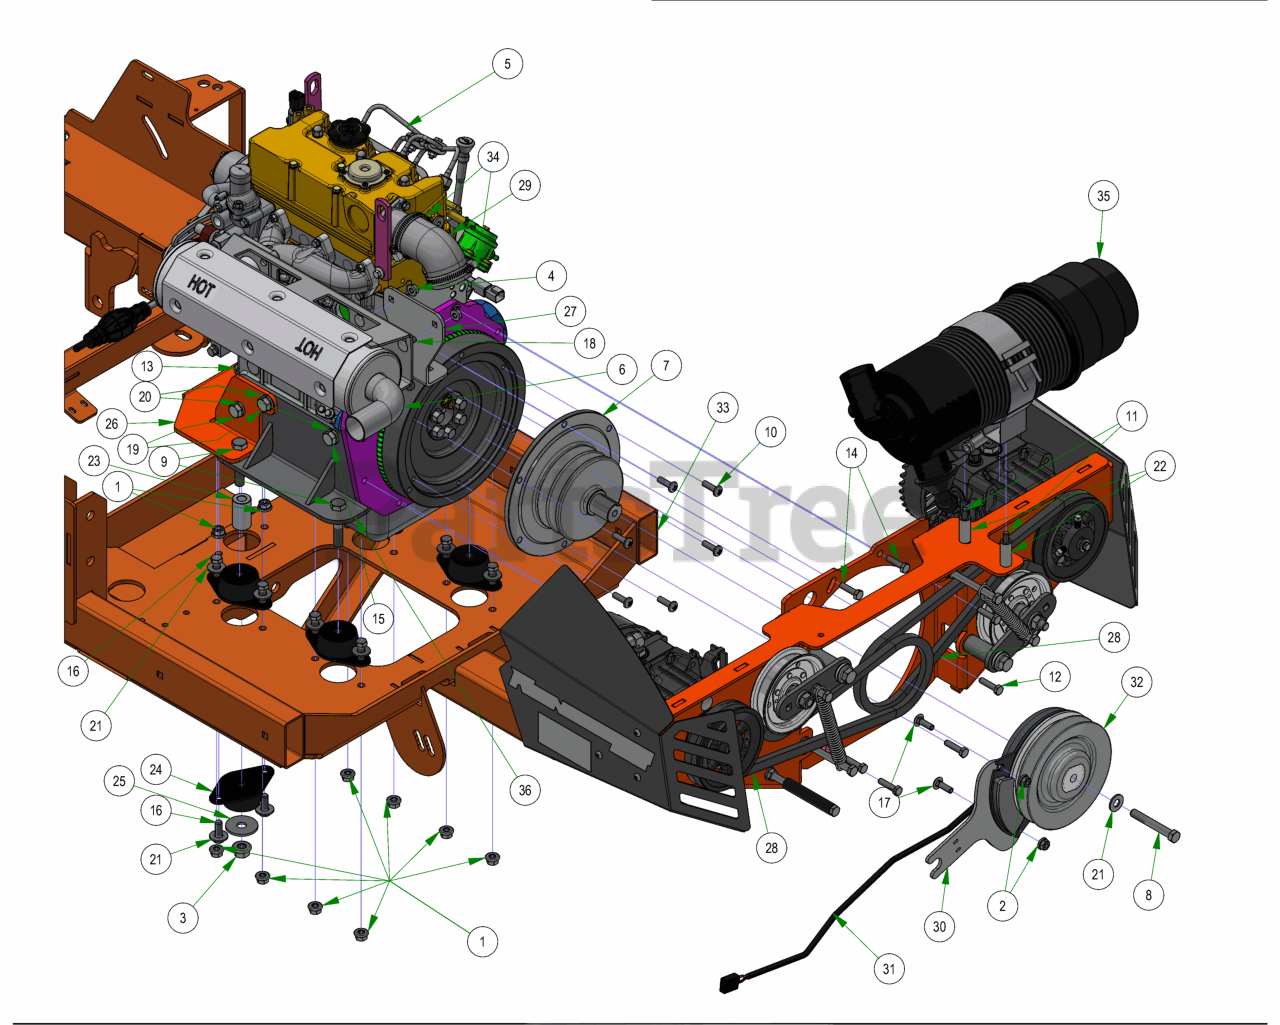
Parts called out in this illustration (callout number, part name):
1	3/8-16 NYLON INSERT FLANGE LOCKNUT (GR.F) ZINC
2	5/16-18 NYLON INSERT FLANGE LOCKNUT ZINC
3	1/2-13 NYLON INSERT FLANGE LOCKNUT ZINC
4	5/16-18 HEX SERRATED FLANGE NUT HARD/ZINC
5	24.7HP Perkins Engine, 403J-11
6	2019 Renegade 1100cc Diesel Muffler
7	2019 Diesel Stub Shaft Double V
8	7/16-20x3” Hex Bolt GR 8 W/ Patch
9	1/2-13 X 2-1/2 HEX CAP SCREW GR 5 ZINC
10	5/16-18 X 1 BUTTON TORX CAP SCREW ZINC
11	5/16-18 X 2-1/4 HEX CAP SCREW (GR.5) ZINC
12	5/16-18 X 1-1/4 HEX C/S (GR.5) ZC
13	1/2-13 X 4 HEX CAP SCREW (GR.8) ZINC YELLOW
14	M8-1.25 X 30MM DIN 933 HEX TAP BOLT (CL 10.9) ZINC
15	M12-1.25 X 25MM DIN 961 HEX TAP BOLT (CL 8.8) ZINC
16	3/8-16 X 1 GR 5 Hex Bolts Zinc
17	5/16-18 X 1 CARRIAGE BOLT (GR.8) ZINC
18	5/16-18 X 7/8 CARRIAGE BOLT ZINC
19	M12-1.25 X 30MM DIN 961 HEX TAP BOLT (CL 8.8) ZINC
20	1/2 SPLIT LOCKWASHER (GR.8) ZINC/YELLOW
21	3/8 FLAT WASHER USS (1" OD) ZINC
22	.380 ID X .625 OD X 1.500 LGTH 2019 OUTLAW BRAKE HANDLE SPACER ZINC
23	1 3/4" Pulley Spacer
24	Rubber Compression Mount
25	.520 ID X 1.750 OD X .120 THICK FLAT WASHER ZINC
26	2022 Renegade Diesel Front Engine Mount
27	2019 Diesel Muffler Bracket
28	2020 Renegade Pump Belt, 42.99"
29	2019 Diesel Air intake Hose
30	2019 Outlaw Renegade Clutch Bracket
31	Clutch Pigtail
32	Clutch for Diesel/Vanguard
33	2022 Horizontal Diesel Frame
34	2-1/2" Hose Clamp
35	Enginaire Canister VLR-Complet
36	2019 Diesel Motor Mount
